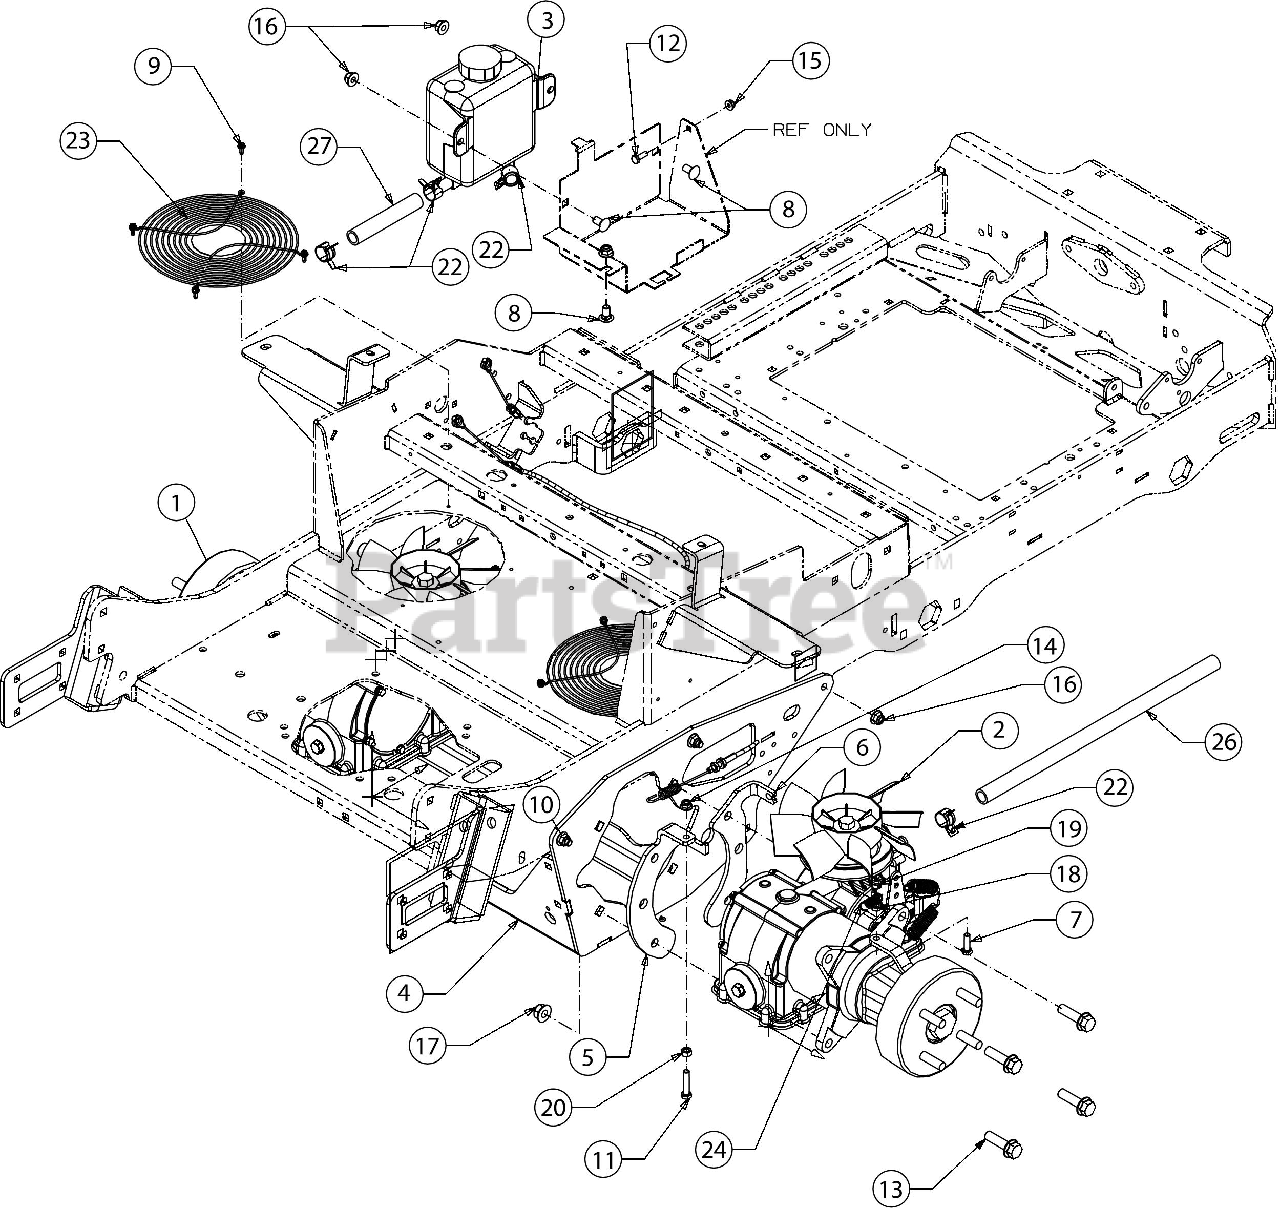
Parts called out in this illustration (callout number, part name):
1	TRANSMISSION ASSEMBLY PARKER (LH)
2	TRANSMISSION ASSEMBLY PARKER (RH)
3	HYDRO TANK ASSEMBLY
4	TRANSMISSION MOUNTING BRACKET ASSEMBLY
5	BRAKE SPRING MOUNTING BRACKET
6	BRAKE CABLE MOUNTING BRACKET
7	SCREW 5/16-18 x 1.0 GR5
8	CARRIAGE BOLT 3/8-16 x .750 GR5
9	SCREW 10-24 x 0.500
10	CARRIAGE BOLT 3/8-16 X1.25 GR5
11	SCREW 5/16-18 x 1.5 LG
12	SCREW 1/4-20X.75 GR5
13	BOLT-1/2-13X1.75LG
14	FLANGE LOCK NUT 5/16-18
15	FLANGE LOCK NUT
19	HEX NUT
20	HEX NUT
22	HOSE CLAMP
24	EXTENSION SPRING .500 OD x 1.71
26	OIL HOSE 5/8 ID X 18.00 LG
27	OIL HOSE 5/8 ID X 5.00 LG
